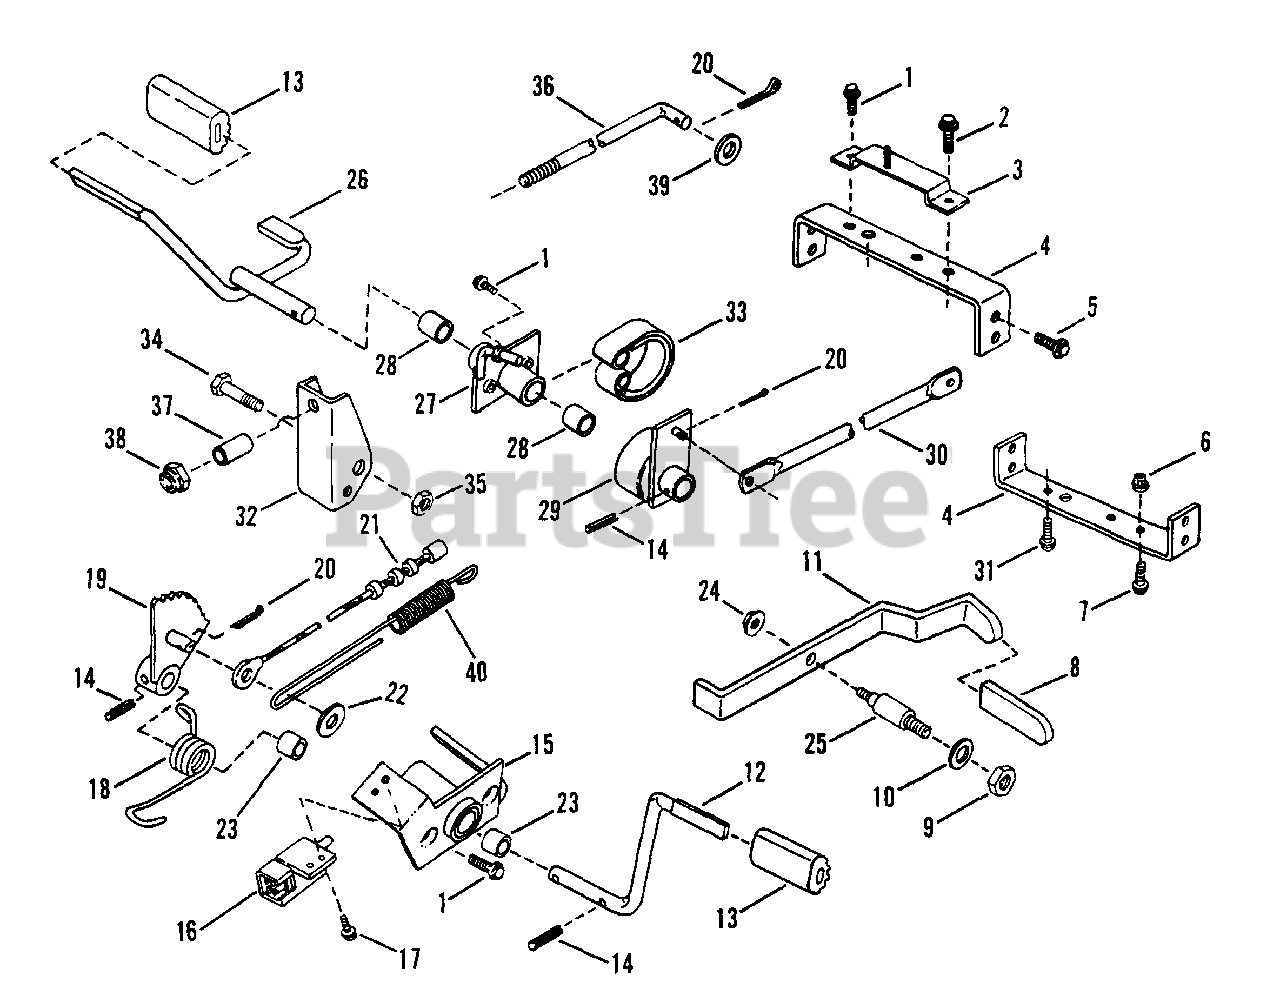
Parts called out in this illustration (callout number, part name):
1	SCREW, 5/16-18 x 5/8" Hex Head, Self-Tapping
2	SCREW, 5/16-18 x 1" Hex Flng. Lk.
3	BRACKET ASSM'Y., Cross Strap
4	STRAP, Cross
5	SCREW, 3/8-16 x 1/2" Hex Washer Head, Self-Tapping
6	NUT, 3/8-16 Hex Flange
7	SCREW, 3/8-16 x 1-3/4" Hex Flange Lock, Grade 5
8	SLEEVE, Parking Brake
9	NUT, 3/8-16 Hex
10	WASHER, 3/8 Internal Tooth Lock
11	LEVER, Parking Brake
12	PEDAL, Neutral Brake
13	PAD, Pedal
14	PIN, 3/16" x 1-1/4" Roll
15	BRACKET, Pedal Pivot
16	SWITCH, Neutral Brake Interlock
17	SCREW, #10-24 x 1/2" H.W.H.S.T.
18	SPRING, Neutral Brake
19	ARM, Neutral Brake
20	COTTER-PIN, 3/32 x 3/4"
21	CABLE, Neutral Brake
22	WASHER, 3/8 SAE Flat
23	BEARING, Sleeve
24	NUT, 1/4-20 Hex, Grade A
25	STUD, Parking Brake
26	ASSEMBLY, Control Pedal
27	ASSEMBLY, Control Pedal Pivot
28	BEARING, DX
29	ASSEMBLY, Control Pedal Arm
30	ROD, Speed Control
31	BOLT, 3/8-16 x 1" Hex Flange Lock
32	LEVER, Friction Control
33	BAND, Brake Assembly
34	BOLT, 1/4-28 x 2" Hex Head, Grade 5
35	NUT, 1/4-28 Hex, Tog Lock
36	ROD, Brake
37	SPACER
38	NUT, 5/16-18 Hex Nyloc
39	WASHER, Flat
